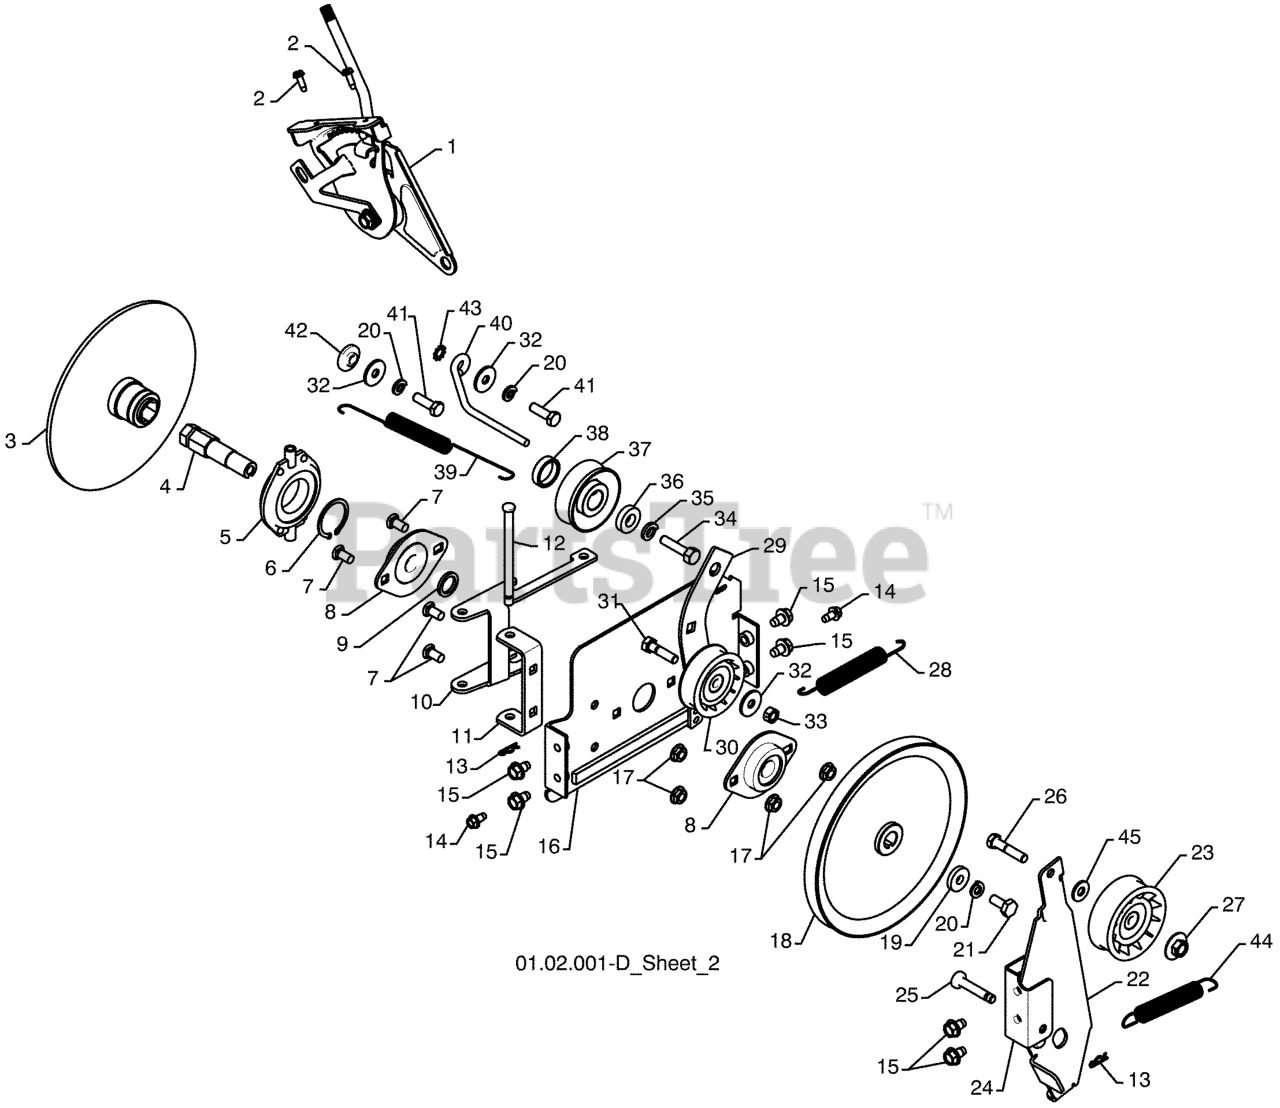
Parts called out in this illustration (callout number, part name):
1	HEAD ASSY SPEED
2	SCREW #10-24 X 5/8
3	DRIVE PLATE WELDMENT
4	SHAFT.HEX.SHORT
5	TRUNNION BEARING ASSY
6	RETAINING RING (2 2)(3 2)
7	BOLT
8	BEARING FLANGE
9	SPACER, BEARING
10	LEVER.SHIFTER.PLATE.BLACK
11	BRACKET, SHIFTER SUPPORT
12	PIN, PIVOT LEVER
13	RETAINER CLIP PM
14	SCREW
15	BOLT 5/16-18 X .500
16	PLATE.DRIVE.MOUNTING.BLACK
17	NUT.FLANGE.5/16
18	PULLEY.TRACTION.7.75
19	WASHER, FLAT
20	WASHER.LOCK.HVY.HLCL.SPR.5/16
21	SCREW 5/16-18 X .750
22	ARM.IDLER.BRAKE.BLACK
23	PULLEY.W/SPACER.2.75
24	BRACKET, IDLER PIVOT
25	PIN, IDLER PIVOT
26	HEX BOLT
27	LOCKNUT 5/16-18
28	RP SPRING, TRACTION IDLER
29	ARM, IDLER
30	PULLEY.W/SPACER.2.25
31	BOLT.5/16-18X1-1/4 FULL.THREAD
32	STEEL WASHER
33	NUT.CENTERLOCK.5/16-
34	SCREW, HEX HD 3/8-24 X 1-3/8
35	LOCKWASHER
36	WASHER, FLAT 3/8
37	PULLEY,ENGINE TRACTION DRIVE
38	SPACER.ENGINE.PULLEY
39	SPRING.RETURN
40	BELT.GUIDE.RH
42	RP BUSHING, IDLER PIVOT
43	WASHER EXT TOOTH LOCK 5/16
44	SPRING, BRAKE
45	WASHER.20X8.5
